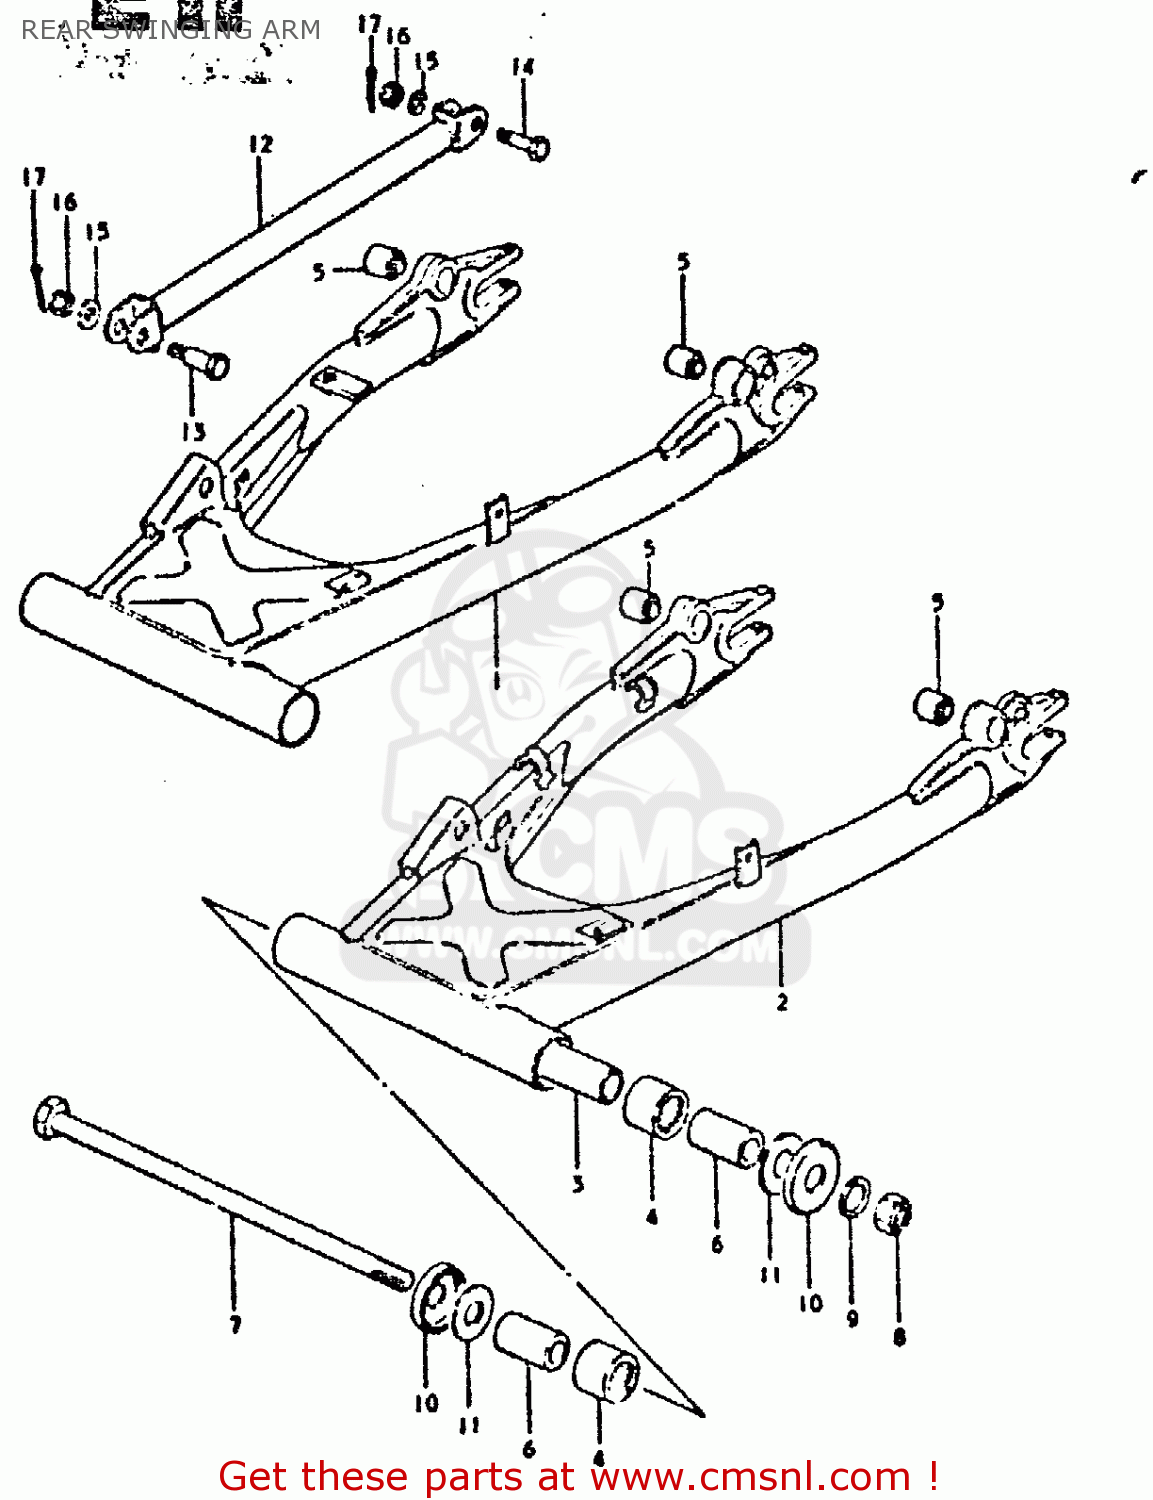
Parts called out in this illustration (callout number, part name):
1	SWING ARM ASSEMBLY,REAR
2	SWING ARM ASSEMBLY,REAR
3	SPACER,RR SWGARM PIVOT CTR
4	BEARING(22X29X30)
5	BUSH
6	SPACER,RR SWGARM PIVOT
7	SHAFT,REAR SWING ARM
8	NUT 14MM
9	WASHER
10	CVR,RR SWGARM DUST SEAL(OD:40)
11	WASHER(14.2X34X1)
12	LINK,REAR TORQUE
13	BOLT
14	BOLT(10X39)
15	WASHER
16	NUT
17	PIN 20X20
